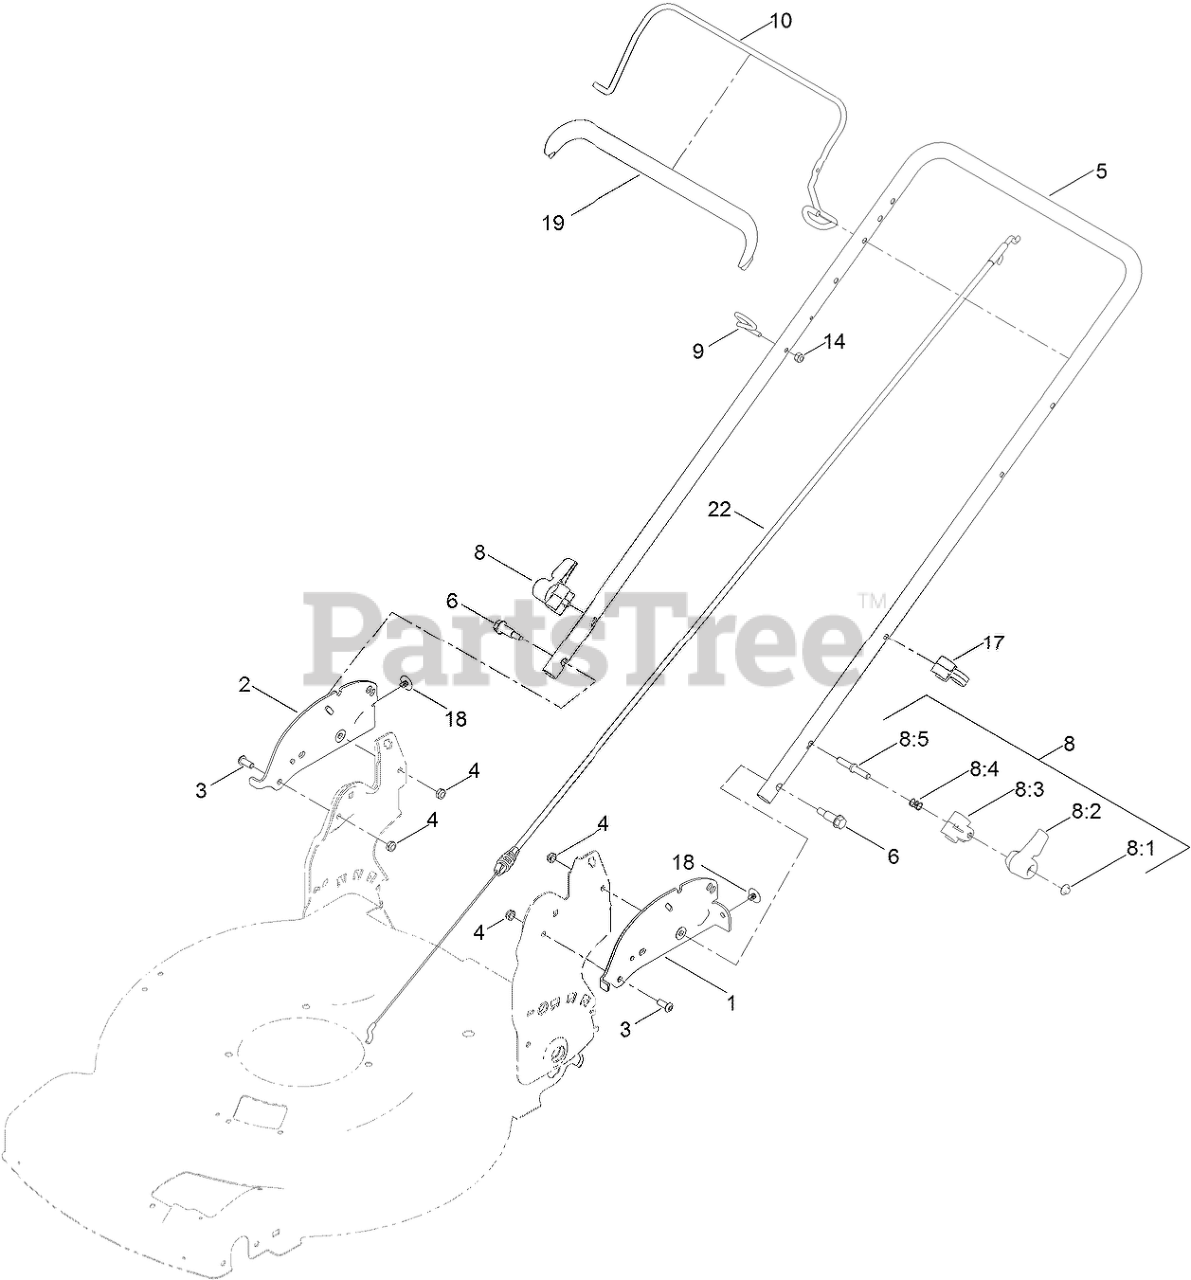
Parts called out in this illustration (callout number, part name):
1	PLATE-HANDLE, LH
2	PLATE-HANDLE, RH
3	SCREW-HSBH
4	NUT-LOCK, NI
6	BOLT-SHOULDER
8	QUICK RELEASE ASM
8:2	LEVER
8:3	ANCHOR-SPRING
8:4	SPRING-COMPRESSION
8:5	ROD-RELEASE
9	GUIDE-ROPE
10	BAIL-BRAKE
14	NUT-LOCK, NI
17	GUIDE-CABLE
18	CLIP-TREE
19	COVER-BAIL
22	CABLE-BRAKE, ENGINE
